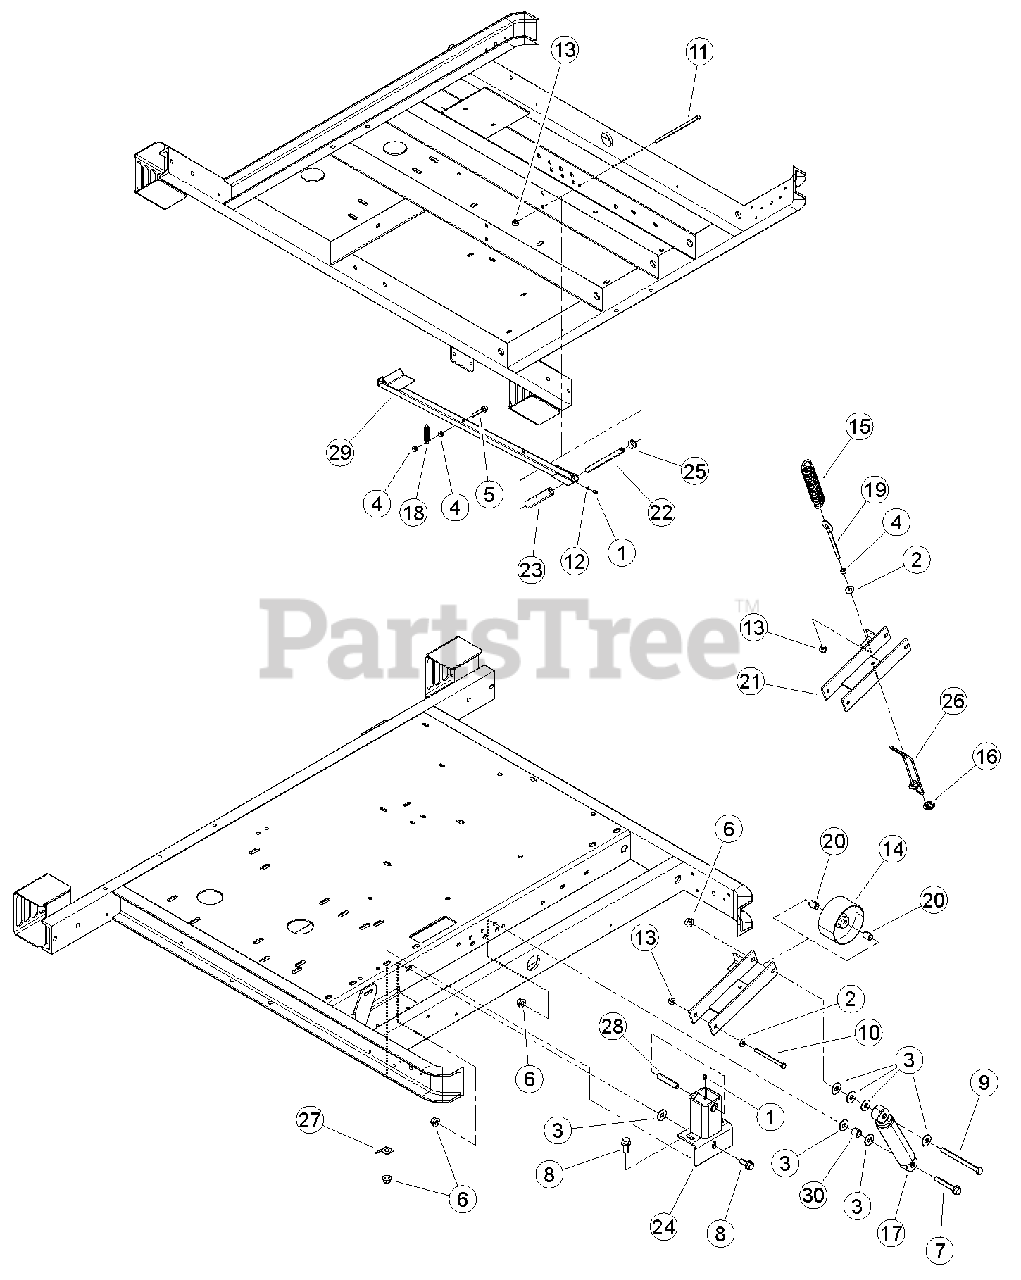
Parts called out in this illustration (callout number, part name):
1	FITTING, 1/4 SELF-TAP GREASE
2	WASHER, 3/8" FLAT ZP
3	WASHER, 1/2" FLAT ZP
4	NUT, 3/8" HEX NC ZP
5	BOLT, 3/8 X 2 FLANGE NC
6	NUT, 1/2-13 NYLOCK FLANGE
7	BOLT, 1/2-13 X 3-1/4 HWH GR8 YZP
8	BOLT, 1/2 -13 X 1-1/4 FLANGE NC
9	BOLT, 1/2 X 6 G5 HCS ZP
10	BOLT, 3/8 X 4-1/2" HHCS GR5 NC ZP
11	BOLT, 3/8 X 7-1/2" HHCS GR5 NC ZP
12	WASHER, FLAT .254 X .400 X .048
13	NUT, 3/8-16 NYLOCK FLANGE
14	PULLEY, IDLER 5 X 2.50"
15	SPRING, 7-3/4" EXTENSION
16	CLAMP, 3/16 CABLE
17	ABSORBER, IDLER SHOCK
18	SPRING, LT EXT .555 OD X 2.75 LG
19	EYEBOLT, 3/8 X 5" LG 4-1/4 THD ZP
20	SPACER, .75 X .90
21	WELDMENT, IDLER ARM
22	SPACER, .63 X 6.44
23	SPACER, 1.0 X 4.25
24	WELDMENT, IDLER SUPPORT
25	SPACER, 1.0 X 0.50
26	CABLE, 3/16 X 24-1/2
27	ANGLE, SPRING ANCHOR
28	SPACER, .63 X 3.06
29	WELDMENT, CHIPPER CLUTCH PEDAL
30	SPACER, 7/8 X 3/4
